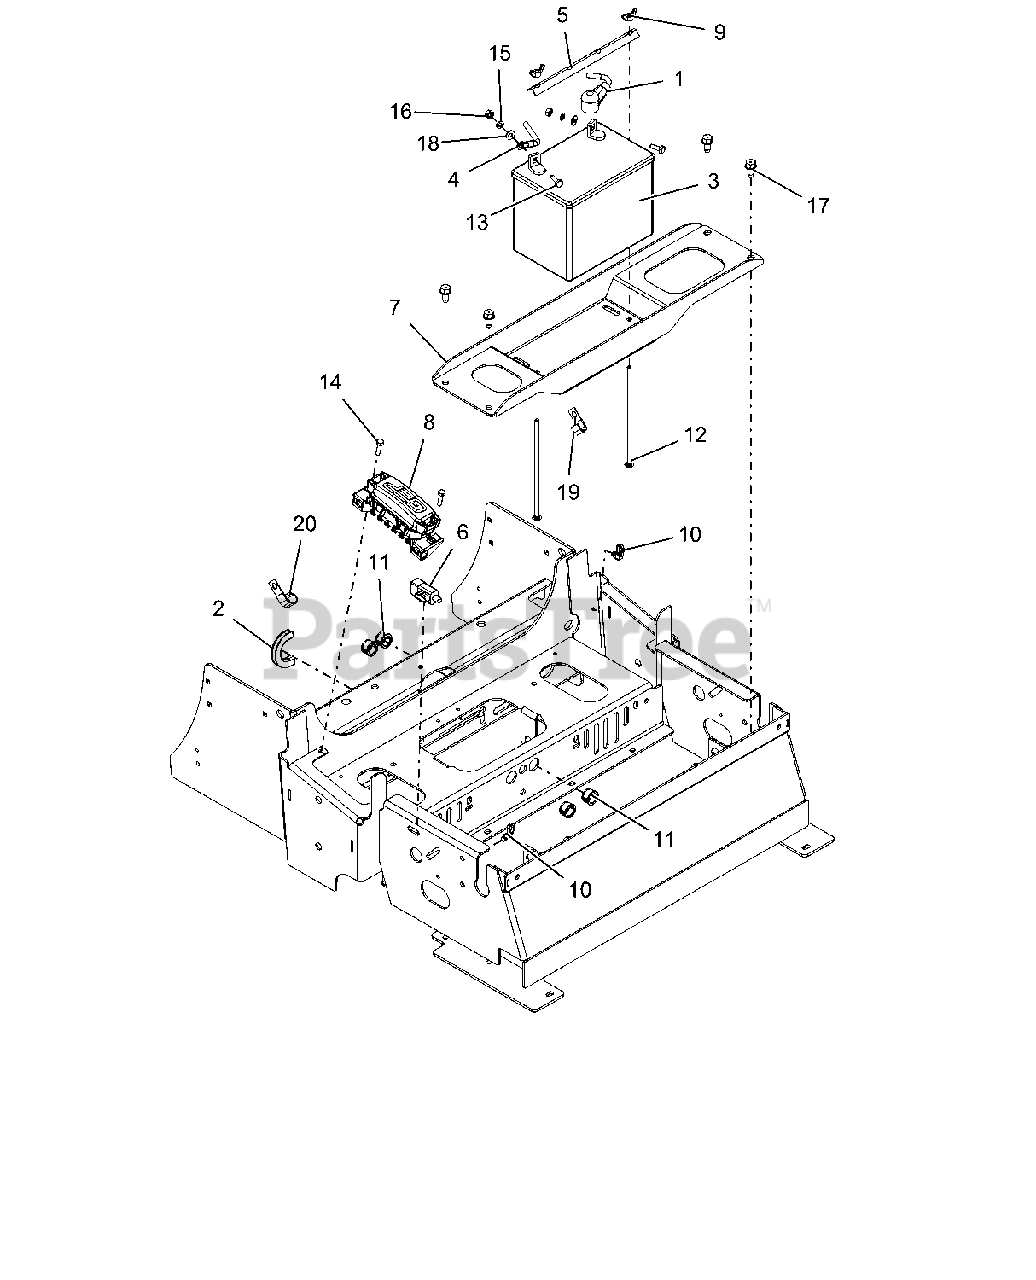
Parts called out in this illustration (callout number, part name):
1	CABLE, POS BATT W/ BOOTS 6 X 35
2	STRIP, COWL - 1.50 LG
3	BATTERY, 300 CCA 10U1L
4	CABLE, NEGATIVE BATTERY 35.00"
5	HOLD DOWN - BLK
6	SWITCH, SNAP IN -N.O./N.O
7	TRAY, BATTERY-RED
8	HARNESS, PT200/400 WIRING
9	NUT-LOCKING WING 1/4-20
10	CABLE TIE W/ TREE (.25 HOLE)
11	BUSH, PANEL SNAP .687X.875X.56
12	BLT-RDHDSQNK .25-20X7.50 G2 YWZC
13	BLT-HEX .25-20X.75 GR5 YWZC
14	@BLT-HEX M6-1.0X25 YWZC
15	WSHR-LK .25X.062 REG YWZC
16	NUT-HEX .25-20 YWZC
17	SCR-TAP .38-16X.75 HWH TR YWZ
18	WSHR-FL-STL.281X.62X.065 YWZC
19	CLAMP, J
